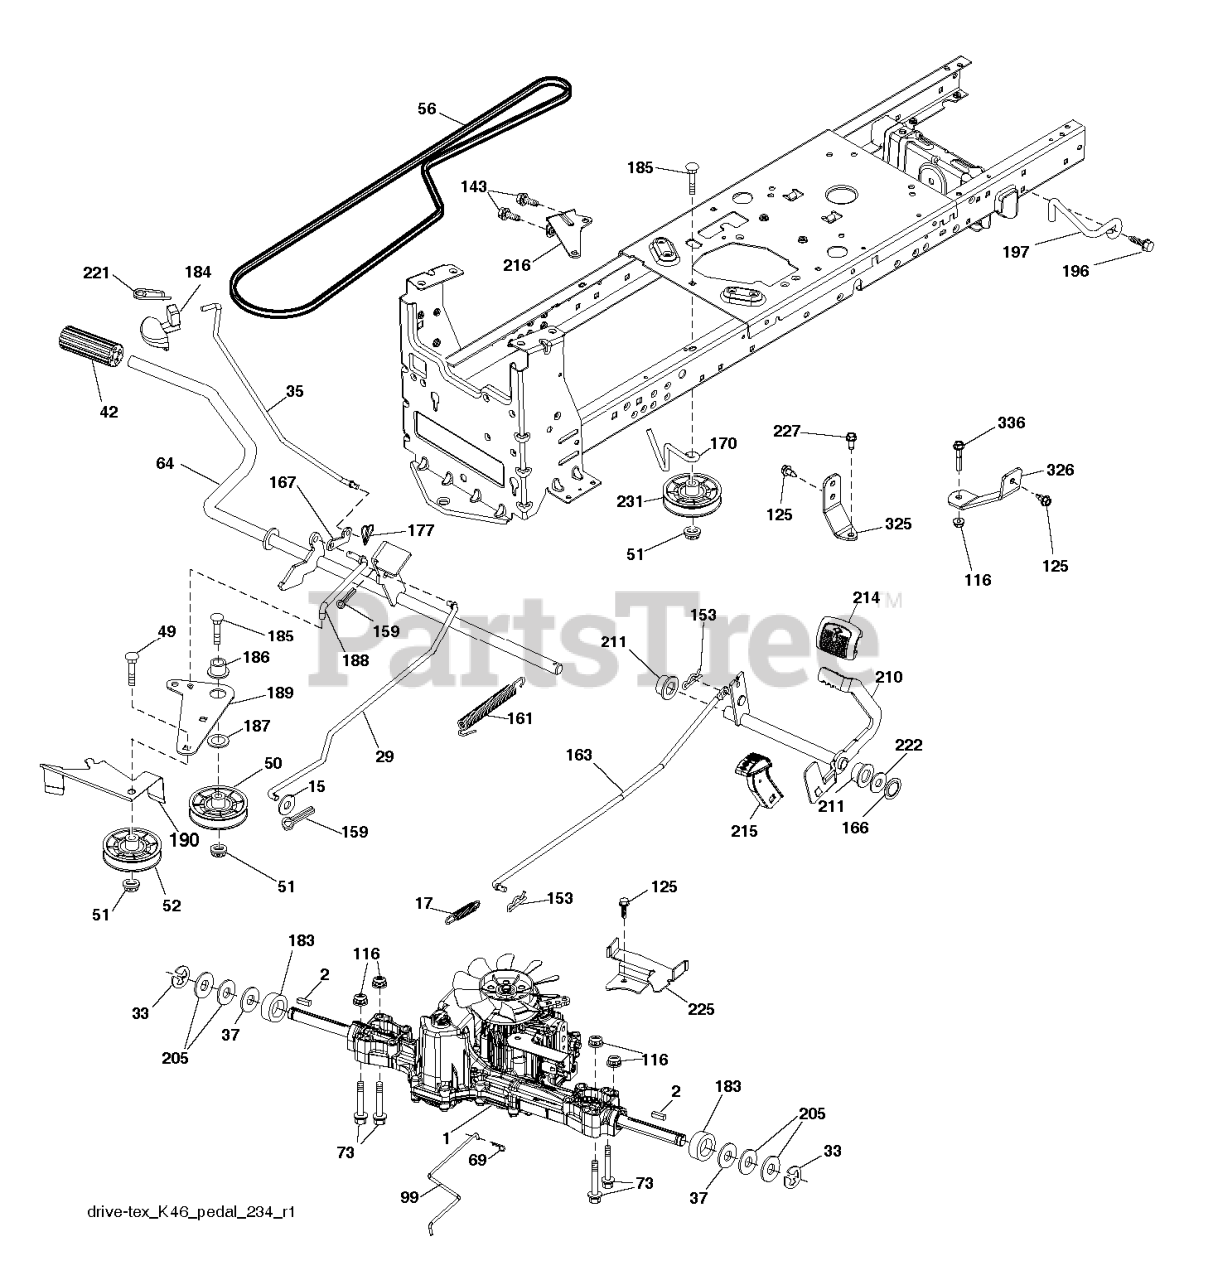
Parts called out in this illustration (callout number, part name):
2	SQUARE KEY
15	WASHER PLAIN WASHER 3/8 X 0.08
17	SPRING.BRAKE.K46.GREEN
29	ROD.BRAKE.K46
37	WASHER.HARDENED
42	PEDAL COVER
50	IDLER.FLAT.910.OFFSET
51	NUT LOCK FLG 3/8-16 UNC
52	IDLER.V-GROOVE.910.OFFSET
64	SHAFT.ASM.PEDAL.BRK.CNTR
69	HAIRPIN.SOFT.ZINC.059X1.125
99	ARM.PIVOTING.TCRD.GEN2.5.BAGGE
125	SCREW
153	RETAINER M
161	SPRING, RETURN LT
166	NUT.PUSH.625
167	LATCH.BRAKE.SPRING
170	KEEPER.CENTER SPAN.1.688
177	PIN COTTER;LOCKING;BOWTIE;1IN
183	SPACER AXLE
184	HANDLE.PARKNG BRK.PRED.LT.428
186	SPACER.RETAINER
188	LINK.CLUTCH.GROUND DRIVE.LONG
189	BELLCRANK.GROUND.DRIVE.TEX.
190	KEEPER.BELLCRANK.DRIVE
196	SCREW 3/8-16X1
210	ROCKER.ASM.PEDAL.CONTR
211	BEARING.NYLON
214	PEDAL.FORWARD.PAD.TEX
215	PEDAL.COVER.REVERSE.CRD.X428BK
216	BRACKET.PULLEY.IDLER.W/TEX
221	RETAINER.SPRING.CLIP.H
222	WASHER 21/32 X 1-1/4 X 10 GA.
225	KEEPER.BELT.TRANSAXLE.K46
231	IDLER.V-GROOVE.1.688.OFFSET
325	BRCKT.PNT.TRQ.STP.46.18TIRE.RH
326	TORQUE.STRAP.K46.LT.LH
